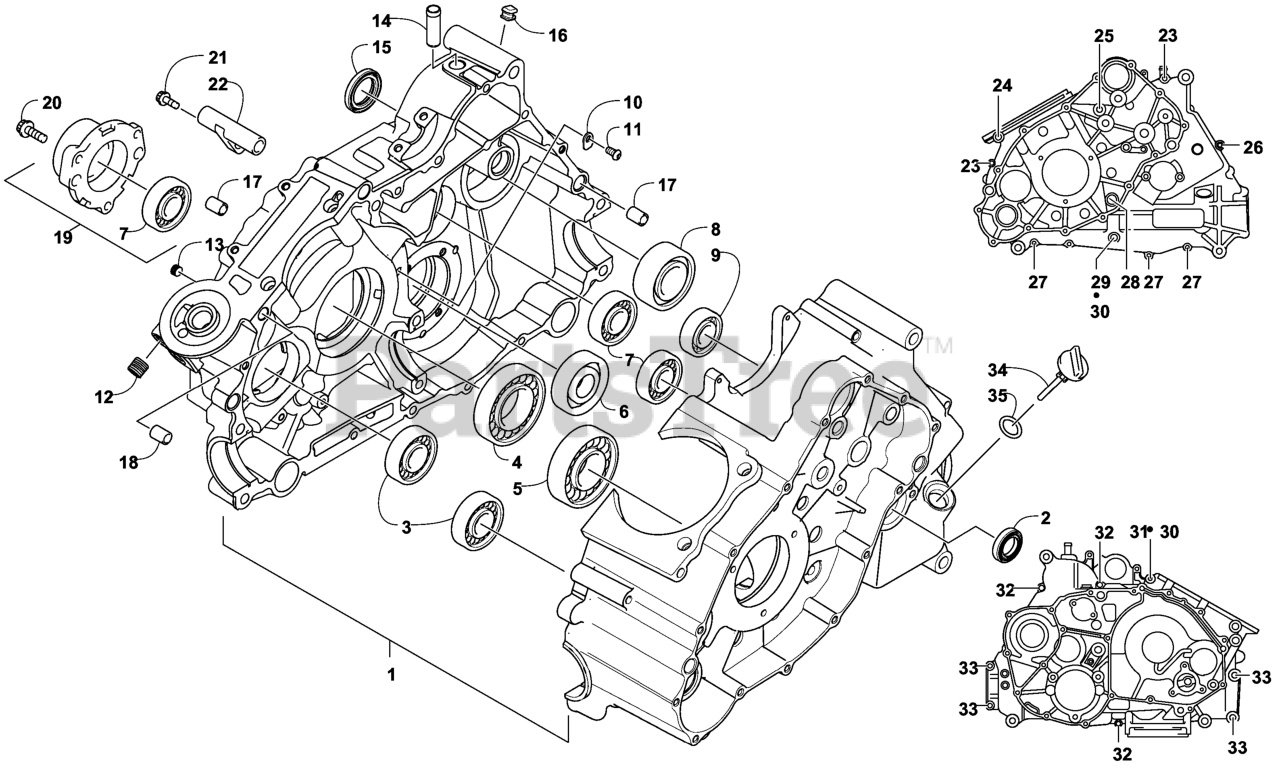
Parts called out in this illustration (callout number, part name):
2	SEAL-COUNTER SHAFT, RH
3	BEARING-CONRAD
4	BEARING-BALL
5	BEARING-BALL
6	BEARING-RADIAL
7	BEARING-CONRAD
8	BEARING-DRIVESHAFT
9	BEARING-CONRAD
10	RETAINER-BEARING
11	SCREW-HSBH
13	PLUG-ENGINE CASE
14	PIPE-BREATHER
15	SEAL-DRIVESHAFT
16	GROMMET
17	DOWEL-SPLIT
18	DOWEL-SPLIT
19	HOUSING-SECONDARY SHAFT
20	SCREW-HFH
21	SCREW-TSPH
22	PIPE-BREATHER
23	SCREW-TSPNH
24	SCREW-HFH
25	SCREW-TSPNH
26	SCREW-TSPNH
28	SCREW-HFH
29	SCREW-HFH
30	GASKET-COPPER
31	SCREW-HFH
32	SCREW-TSPNH
33	SCREW-HFH
34	STICK-OIL LEVEL
